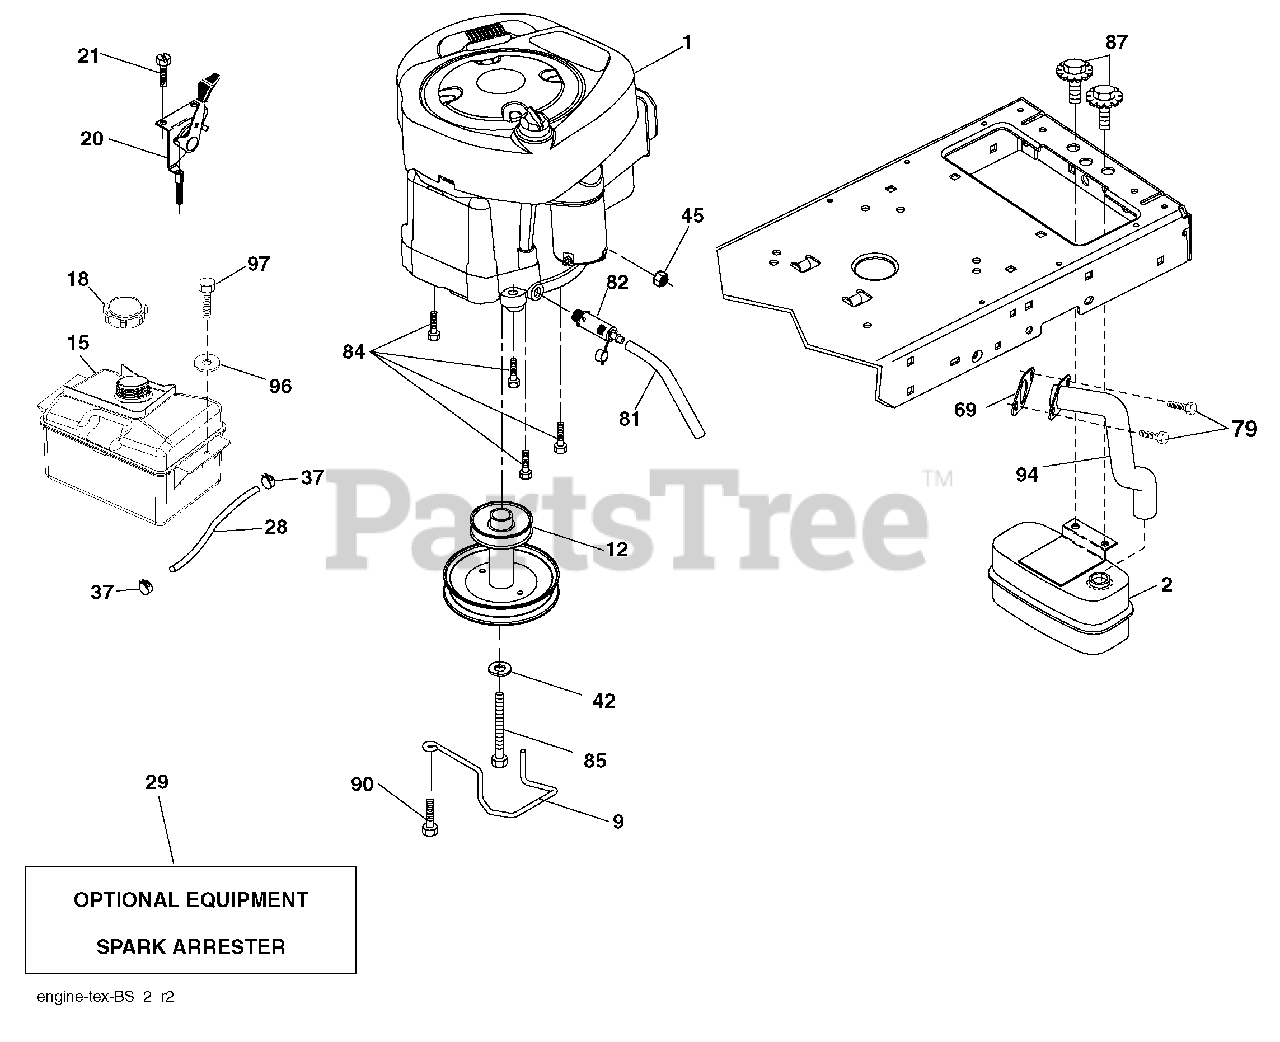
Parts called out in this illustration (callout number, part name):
9	Keeper Belt Engine
12	Pulley Engine
15	Tank Fuel
18	Cap Asm
20	Control Throttle
21	Screw #10 x 0.750 BOS Thread
28	Fuel Line
29	Spark Arrester Kit
37	Clamp Hose
42	Washer Lock 7/16
45	Nut Keps Hex 1/4-20 unc
69	Gasket
79	Screw 5/16-18 x 3/4
81	Tube Drain Oil Easy
82	Valve Drain Oil
84	Screw 3/8-16 x 1/4
85	Bolt Hex 7/16-20 x 4 Gr. 5
87	Bolt 5/16-18 unc x 3/4 w/sems
90	Screw 3/8-16 x 1
94	Exhaust Tube
96	Washer 9/32 x 7/8 x 16 Ga.
97	Screw 1/4-20 x 3/4
